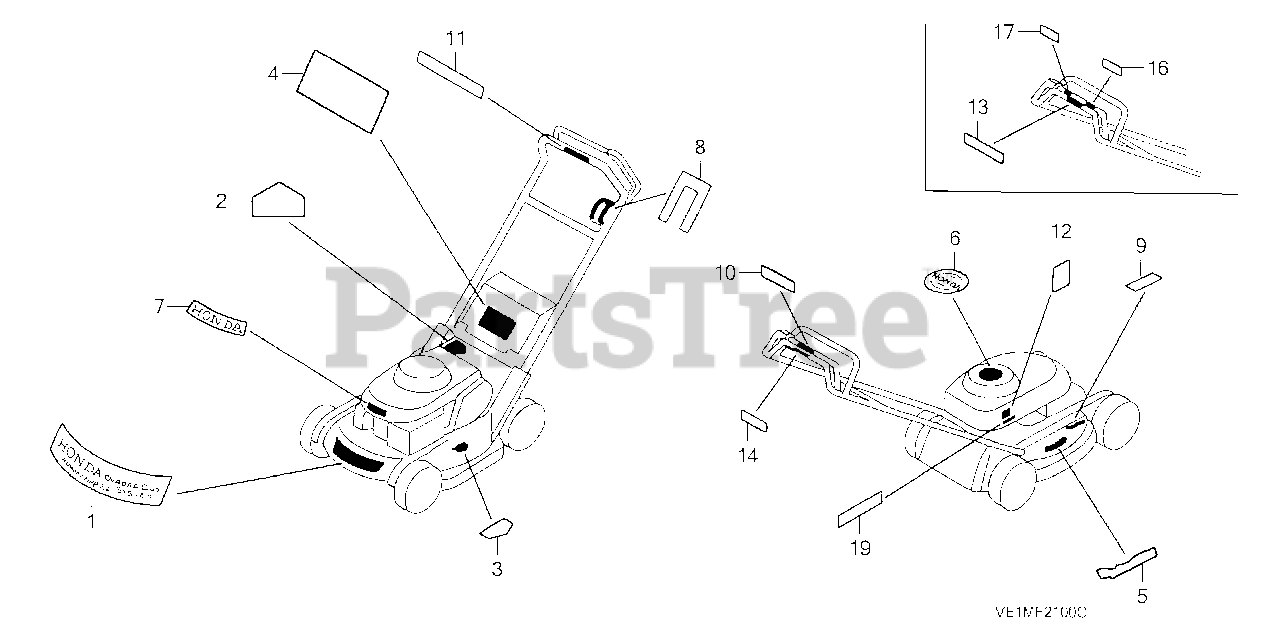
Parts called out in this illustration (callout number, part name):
1	MARK, EMBLEM (HRB216)
2	CAUTION C, HOUSING
3	LABEL, STEP POSITION (ENGLISH)
4	LABEL, WARNING (ENGLISH)
6	MARK, RECOIL COVER
7	MARK, HONDA
8	MARK, THROTTLE INDICATION (ENGLISH)
9	LABEL, HEAT WARNING
10	MARK, BLADE CONTROL
12	MARK, OIL CAUTION
14	MARK, CLUTCH INDICATION (ENGLISH)
